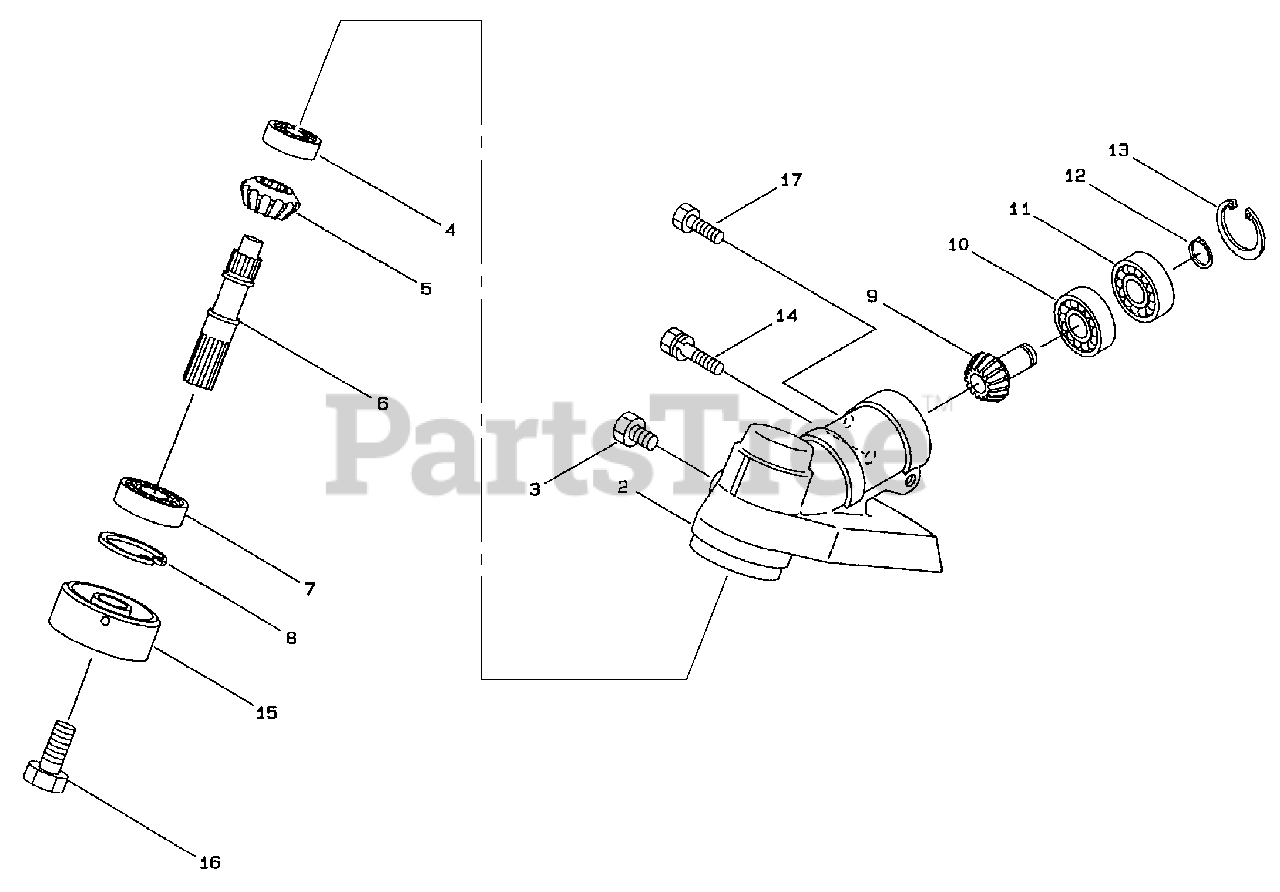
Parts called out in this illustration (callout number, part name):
2	Gearcase
6	Blade Shaft
8	Snap Ring
9	Pinion Gear
12	Snap Ring
13	Snap Ring
15	Boss Adapter
